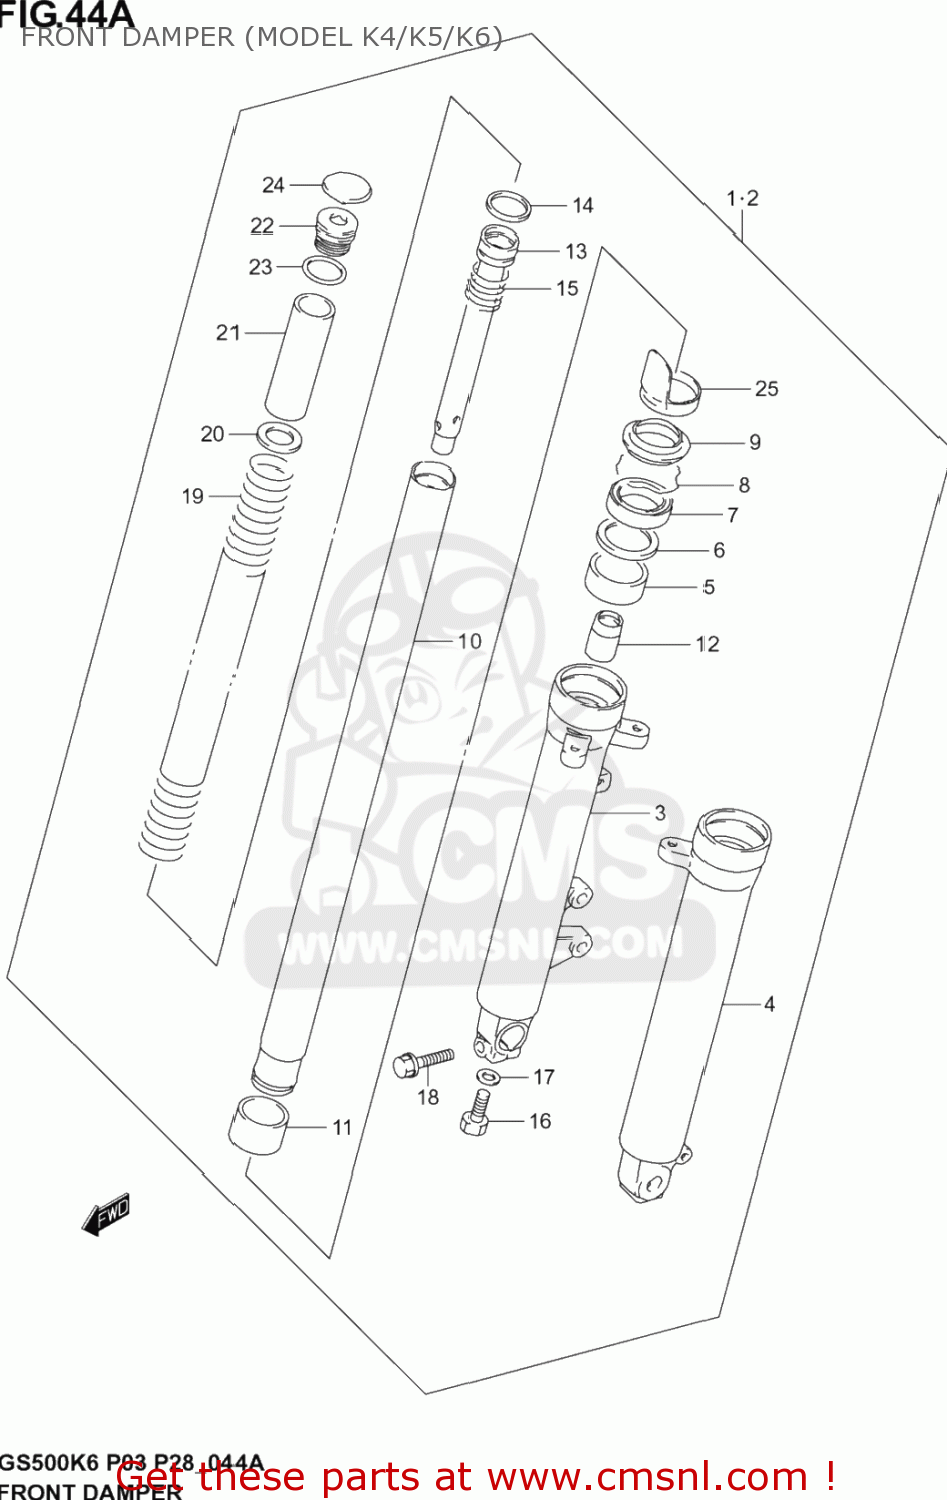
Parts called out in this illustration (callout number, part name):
1	DAMPER ASSY RH
2	DAMPER ASSY LH
3	TUBE, OUTER RH
4	TUBE, OUTER LH
5	METAL, SLIDE
6	WASHER
7	SEAL, OIL
8	RING, SNAP
9	SEAL, DUST
10	TUBE, INNER
11	PISTON
12	PIECE, OIL LOC
13	CYLINDER
14	RING, PISTON
15	SPRING, REBOUN
16	BOLT
17	GASKET (NAS)
18	BOLT RH
19	SPRING, MAIN
20	WASHER, SPRING
21	SPACER
22	CAP
23	O RING
24	PROTECTOR
